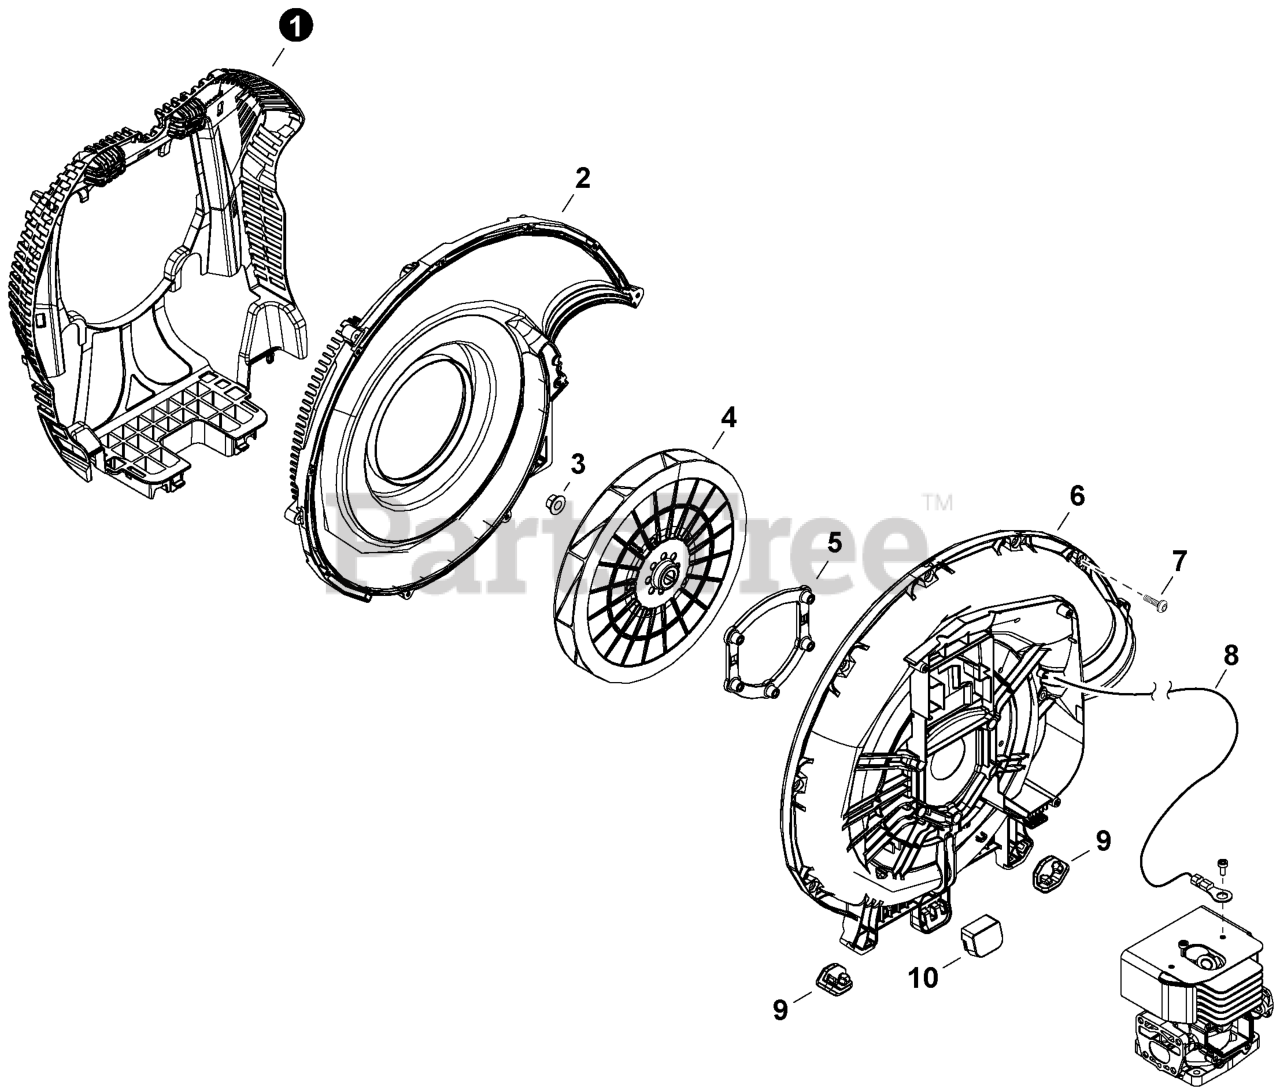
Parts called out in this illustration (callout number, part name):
1	GUARD, DEBRIS
2	COVER, FAN
3	NUT, FLANGE 10x1.25
4	FAN, BLOWER
5	PLATE, ENGINE
6	CASE, FAN
7	BOLT, TORX 5x20
8	WIRE, ANTI-STATIC
9	CUSHION
10	CUSHION
